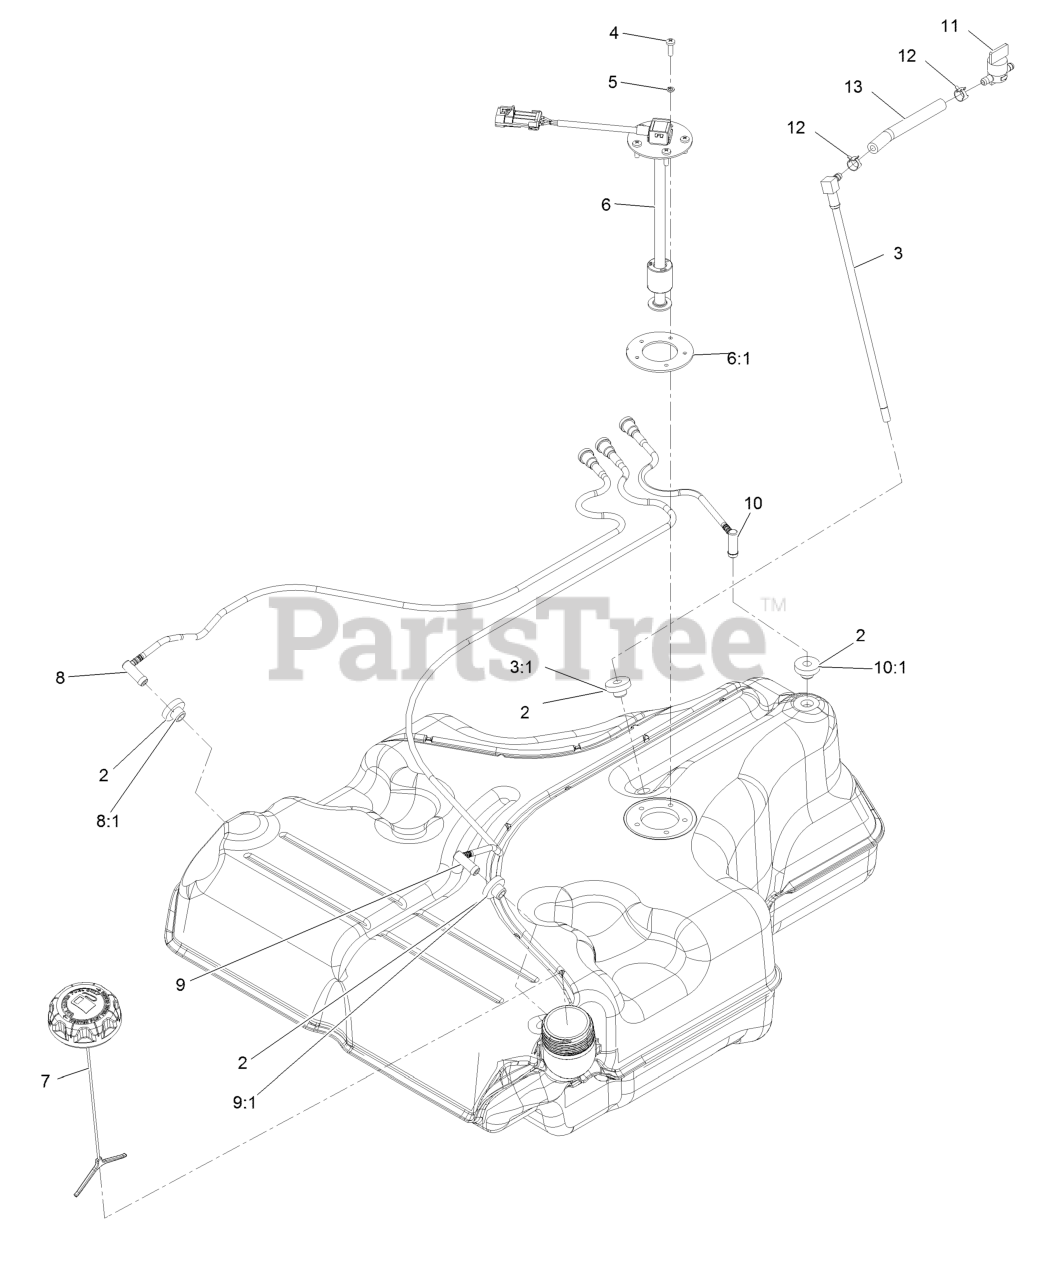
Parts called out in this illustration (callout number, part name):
2	Bushing
3	Fuel Line Kit (With Grommet)
3:1	Bushing
4	Screw-PPH
5	Washer-Lock
6	Float-Sender, Fuel
6:1	Gasket-Sender
7	Cap-Fuel, Ratcheting
8	RH Vent Line Kit (With Grommet)
8:1	Bushing
9	LH Vent Line Kit (With Grommet)
9:1	Bushing
10	Rear Vent Line Kit (With Grommet)
10:1	Bushing
11	Valve-Fuel
12	Clamp-Hose
13	Hose-Fuel
